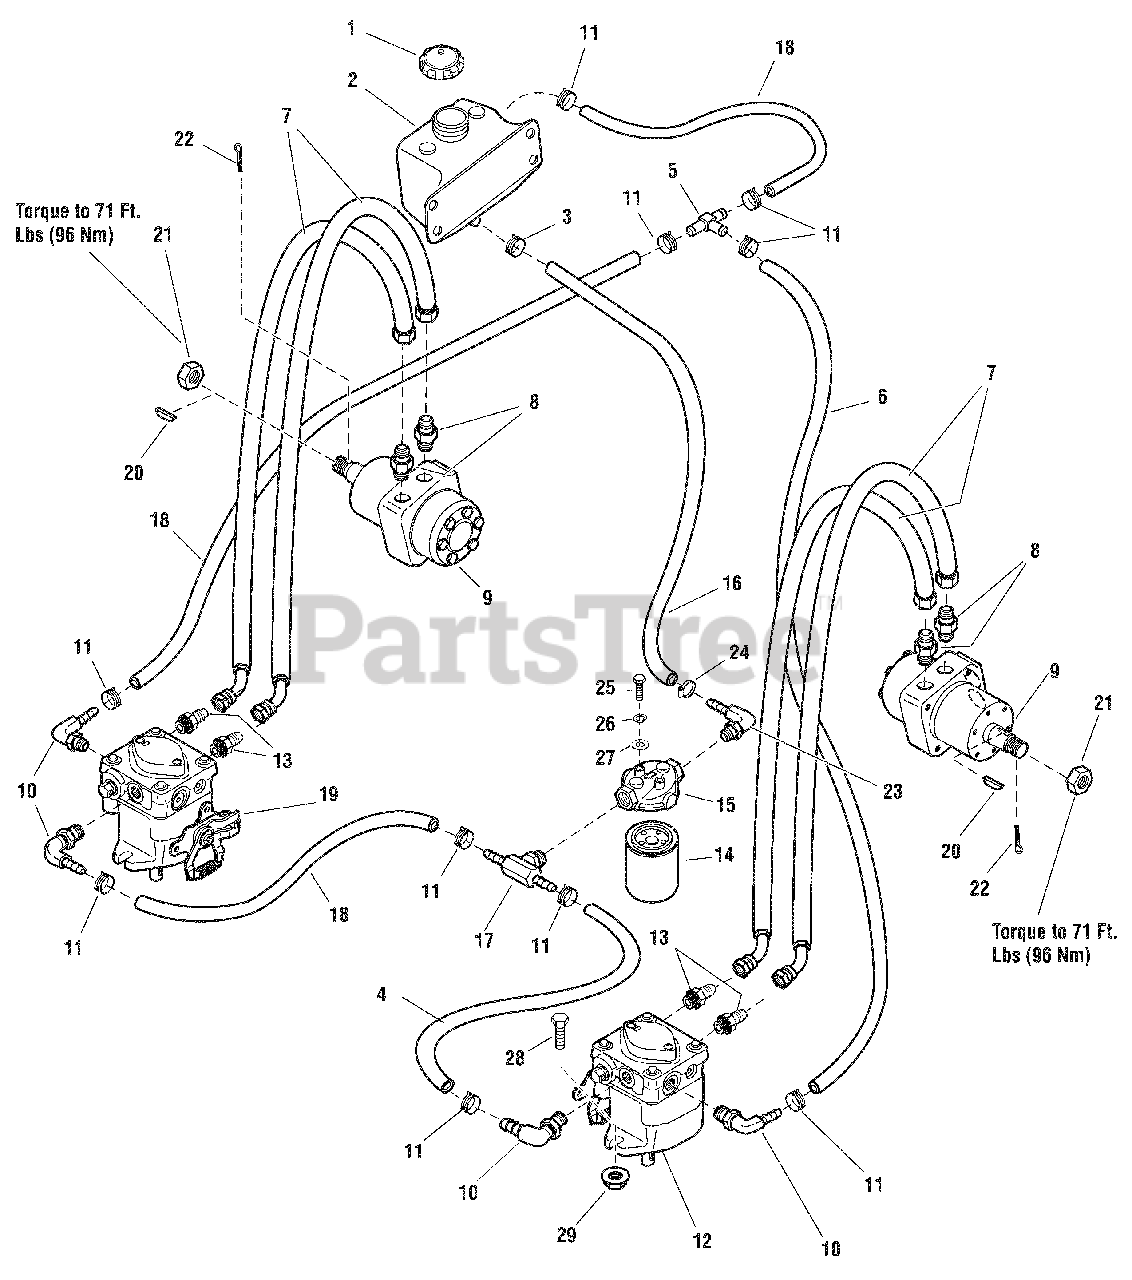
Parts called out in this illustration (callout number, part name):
1	CAP, HYDRAULIC RESERVOIR
2	TANK, 2 QT HYDRAULIC
3	CLAMP, HOSE, 7/8
4	HOSE, 3/8" PUSH-LOCK, 8.50"
5	FITTING, TEE, 1/2" HOSE
6	HOSE, 3/8 PUSH-LOCK, 27
7	HOSE ASSEMBLY (19")
8	ADAPTER, HYD.
9	MOTOR, WHEEL
10	ADAPTER, 90 DEG, 9/16-3/8 BARB
11	CLAMP, HOSE
12	PE, 10CC HYDRAULIC PUMP - LH
13	ADAPTER, HYD.
14	FILTER, OIL
15	FILTER HEAD, HYDRAULIC
16	HOSE, 5/8 PUSH-ON, 12.50" LONG
17	ADAPTER, TEE, 9/16-3/8 BARB
18	HOSE, 3/8" PUSH-LOCK, 7.50"
19	PE, 10CC HYDRAULIC PUMP - RH
21	NUT, CASTLE
22	PIN, COTTER, 1/8" X 1-1/4
23	ADAPTER, 90 DEG, 9/16-5/8 BARB
24	CLAMP, #10 HOSE, STAINLESS
25	BOLT, 1/4-20 X 3/4" GD5 YZ
26	WASHER, 1/4" LOCK
27	WASHER, 1/4 SAE (5025154)
28	BOLT, 3/8-16 X 1-1/4" GD5
29	NUT, 3/8-16 HEX SERRATED FLANGE
30	KIT, Castle Nut & Cotter Pin
